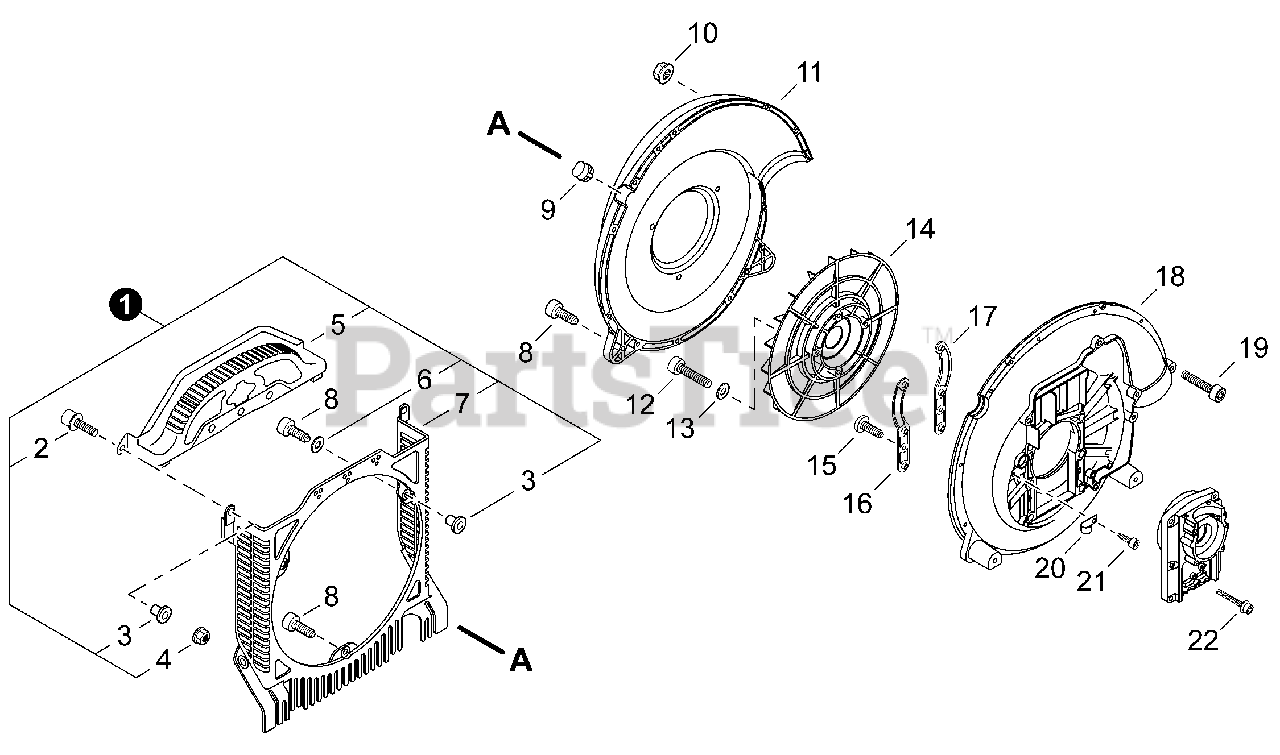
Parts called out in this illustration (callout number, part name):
1	GUARD KIT, DEBRIS
2	BOLT 5×20
4	NUT, LOCK M5
5	SHIELD, DEBRIS - UPPER
6	WASHER 5.5×16×2T
7	SHIELD, DEBRIS - LOWER
8	SCREW TAPPING 5×20
9	PLUG, FAN CASE
10	NUT, FLANGE M5
11	COVER, FAN
12	BOLT 6×35
14	FAN, BLOWER
15	SCREW 5×14
16	PLATE, ENGINE (A)
17	PLATE, ENGINE (B)
18	CASE, FAN
19	BOLT 5×60
21	SCREW TAPPING 5×16
22	SCREW 6×35
